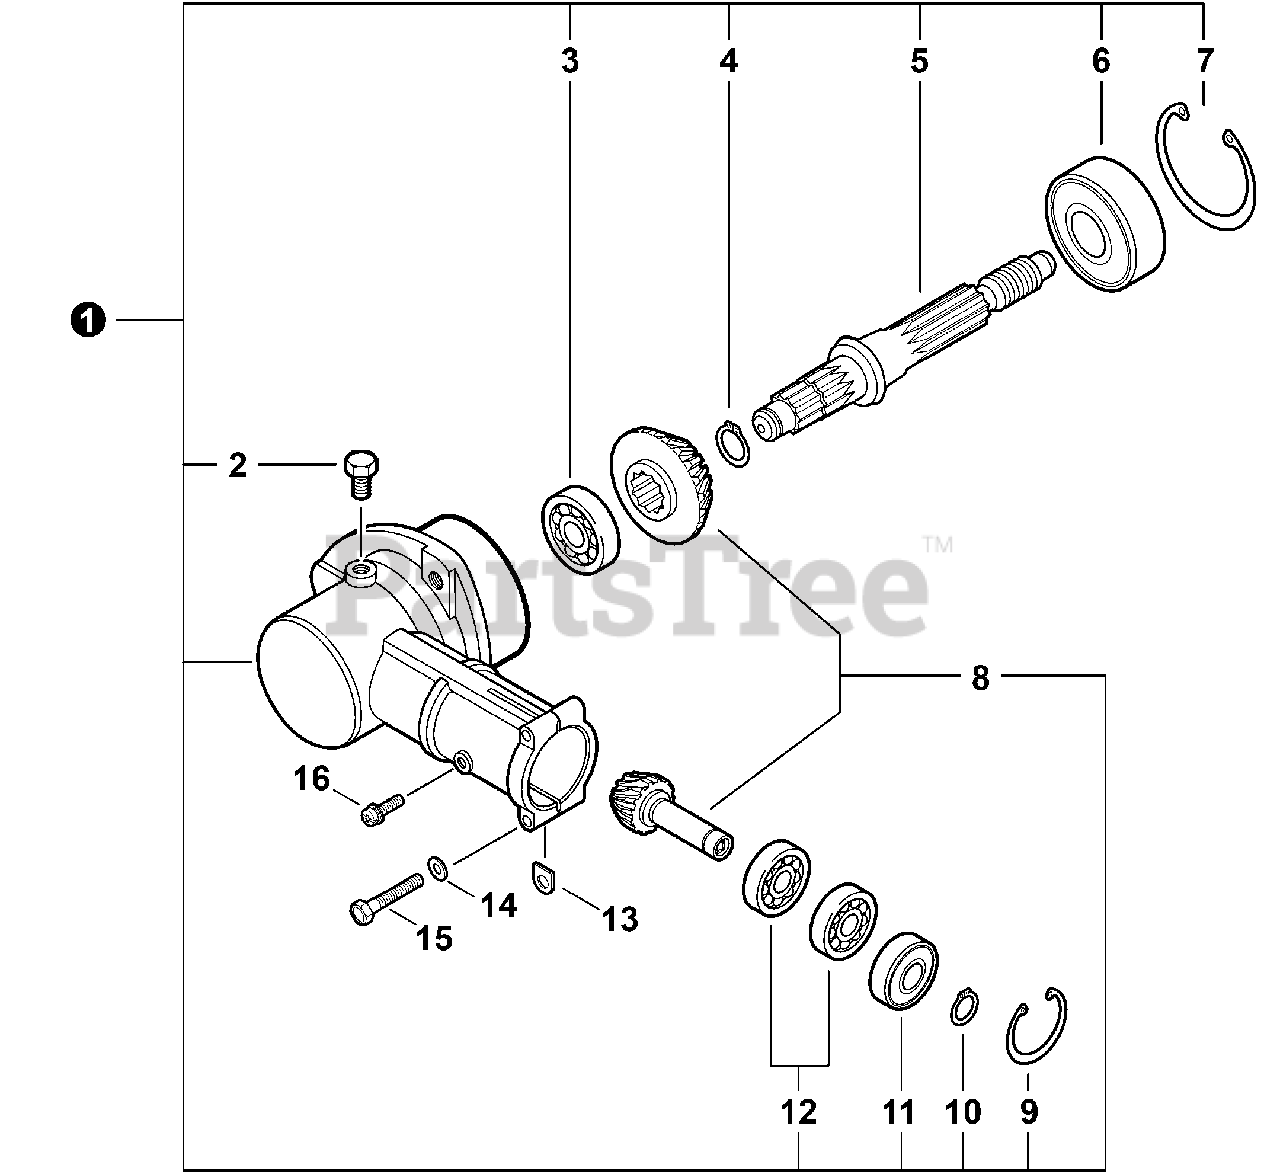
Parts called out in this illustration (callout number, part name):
1	GEAR CASE ASY
2	BOLT - 8×8
3	BEARING, BALL - 629
4	RING, RETAINING - 12
5	GEAR, SHAFT
6	BEARING, BALL - 609
7	RING, RETAINING - 42
8	GEAR SET
9	RING, RETAINING - 22
10	RING, RETAINING - 10
11	BEARING, BALL - 6900Z
12	BEARING, BALL - 6900
13	WASHER, SHIM
15	BOLT - 5×30
16	SCREW - 5×12
